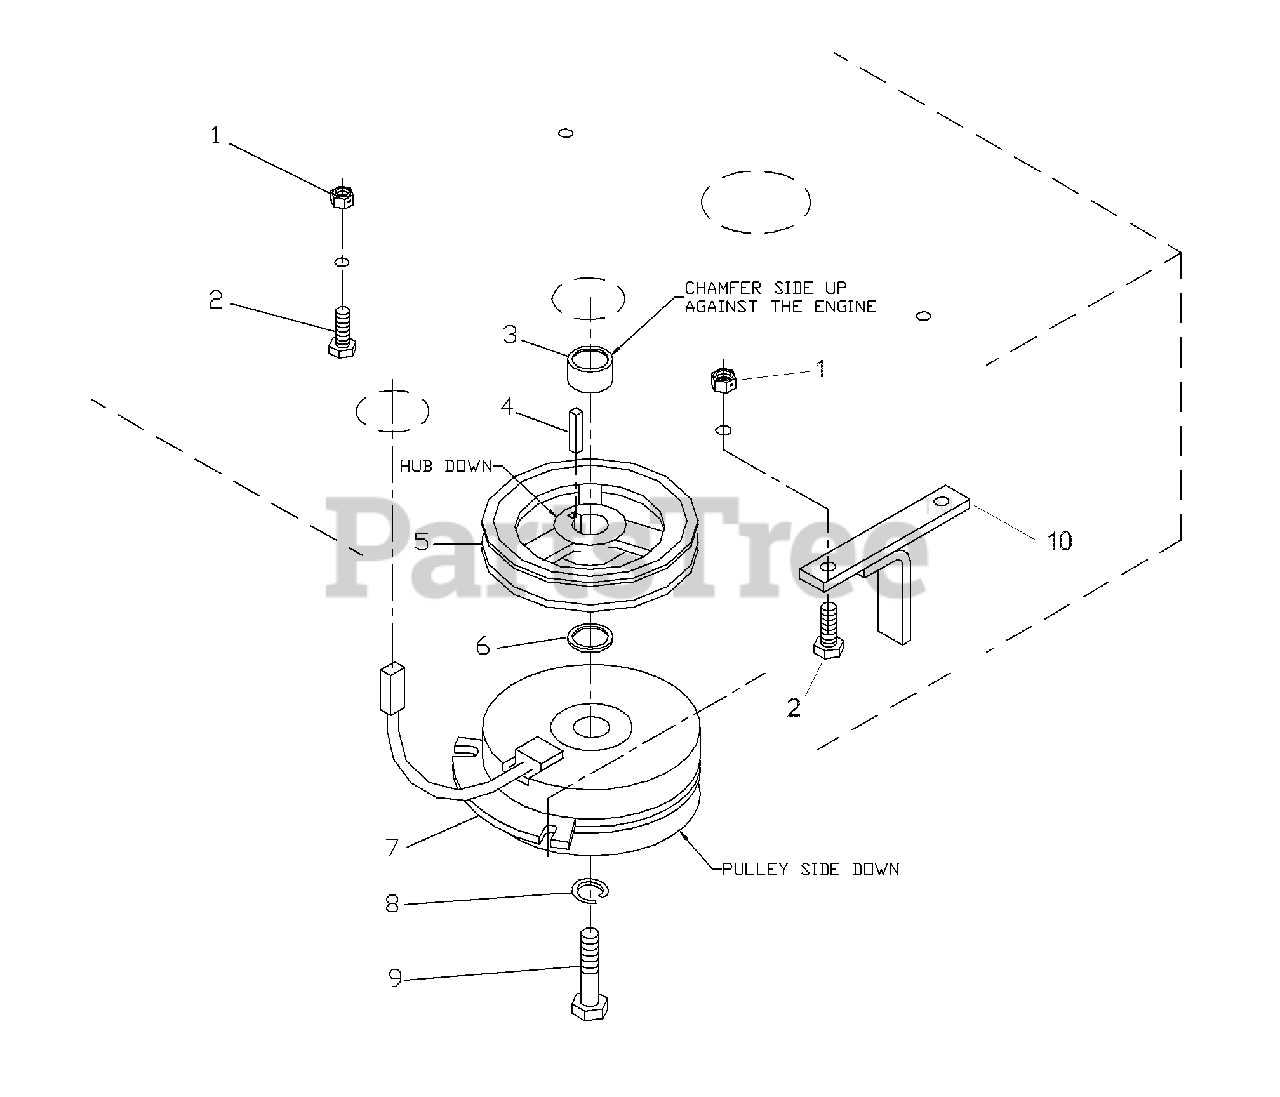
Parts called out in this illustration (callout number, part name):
1	NUT 5/16C CENTERLOCK
2	HCS 5/16C X 1 3/4
4	KEY 1/4 SQ. X 1 1/8
6	10GA. MACHINERY BUSHING
7	ELECTRIC CLUTCH
8	7/16 LOCKWASHER
9	HCS 7/16F X 2 1/2
10	CLUTCH TIE DOWN
